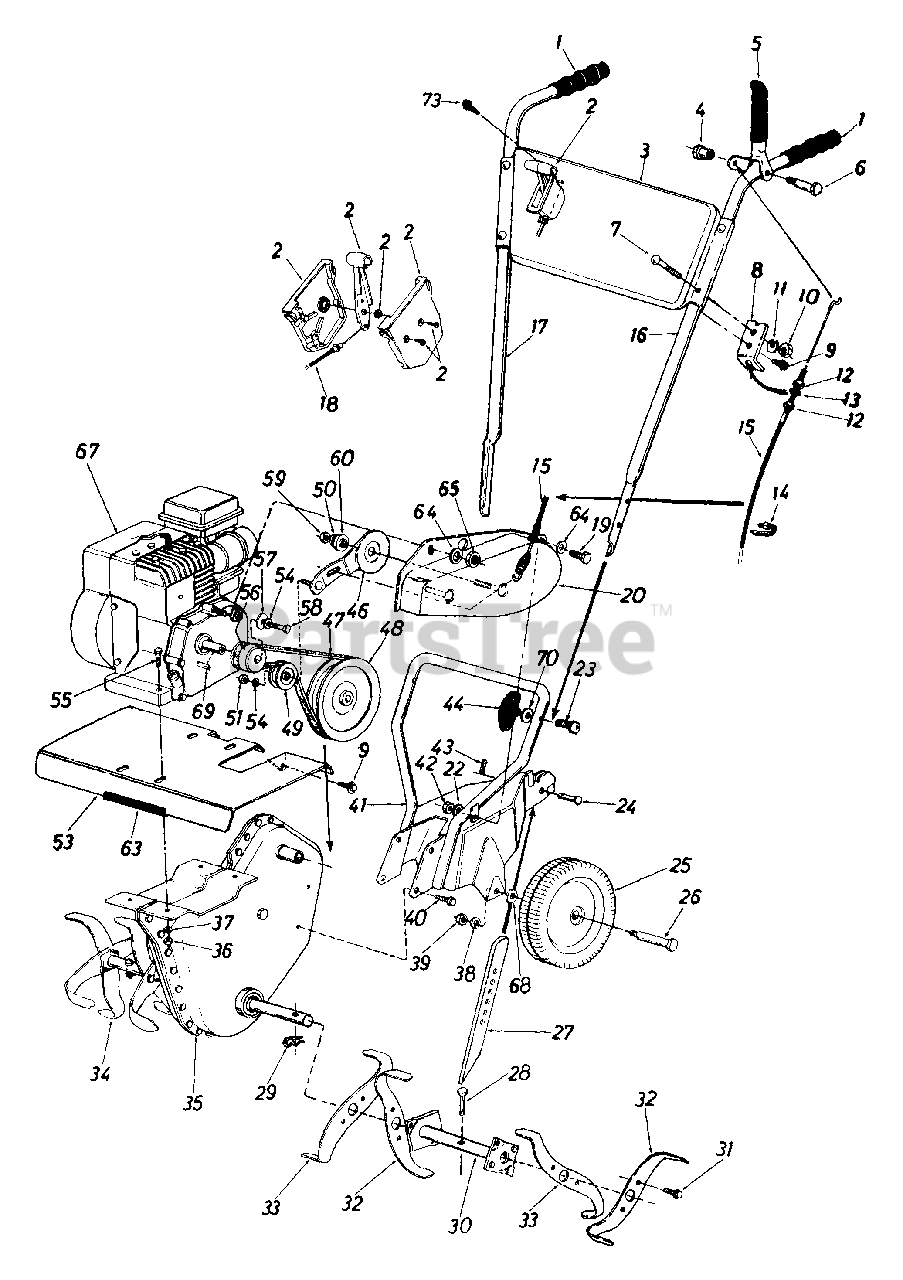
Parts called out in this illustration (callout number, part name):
2	Throttle Control Box Ass'y.
3	Handle Panel
4	Shoulder Nut
5	Clutch Grip Ass'y.
6	Shoulder Bolt 3/8" x 1.16
7	Carriage Bolt 5/16-18 x 1.5" Lg.
8	Cable Support Bracket
9	Hex Wash. Hd. Self-Tap Scr. 1/4-20 x .50" Lg.
10	Hex Nut 5/16-18 Thd.
11	L-Wash. 5/16" I.D.
12	Hex Jam Nut 5/16-24 Thd.
13	L-Wash. 5/16" I.D.
14	Cable Tie
15	Clutch Control Cable
19	Hex Bolt 1/4-20 x .75" Lg.
20	Belt Cover Ass'y.
22	L-Wash. 1/4" I.D.
23	Curved Hd. Bolt 5/16-18 x 1.75" Lg.
24	Clevis Pin
25	Wheel Ass'y. Comp.- Plastic
26	Shoulder Bolt
29	Hairpin Cotter
36	Hex Nut 5/16-18 Thd.
37	L-Wash. 5/16" I.D.
38	L-Wash. 3/8" I.D. (Heavy Duty)
39	Hex Cent. L-Nut 3/8-16 Thd.
40	Hex Wash. Hd. Self-Tap Scr. 5/16-18 x .50" Lg.
43	Internal Cotter Pin
44	Hand Knob
46	Idler Arm Ass'y.
47	Belt
48	Chain Case Pulley 5 1/2" x 1/2"
49	Fl-Idler 2"
50	L-Wash. 5/16" I.D.
51	Hex Nut 3/8-24 Thd.
55	Hex Bolt 5/16-18 x 1.5" Lg.
56	Engine Pulley 3/8" V
57	Fl-Wash. .385" I.D. x 1" O.D.
58	Hex Bolt 3/8-24 x 1" Lg.
59	Hex Nut 5/16-18 Thd.
60	Shld. Spacer .50" Dia.
63	Trim Strip - 4 1/2"
64	Fl-Wash. .281" I.D. x .5" O.D.
65	Hex Cent. L-Nut 1/4-20 Thd.
67	Engine
68	Bell-Wash.
69	Square Key 3/16" x 3/4" Lg.
70	Bell-Wash.
73	Self-Tap Screw #10 x .5" Lg.
